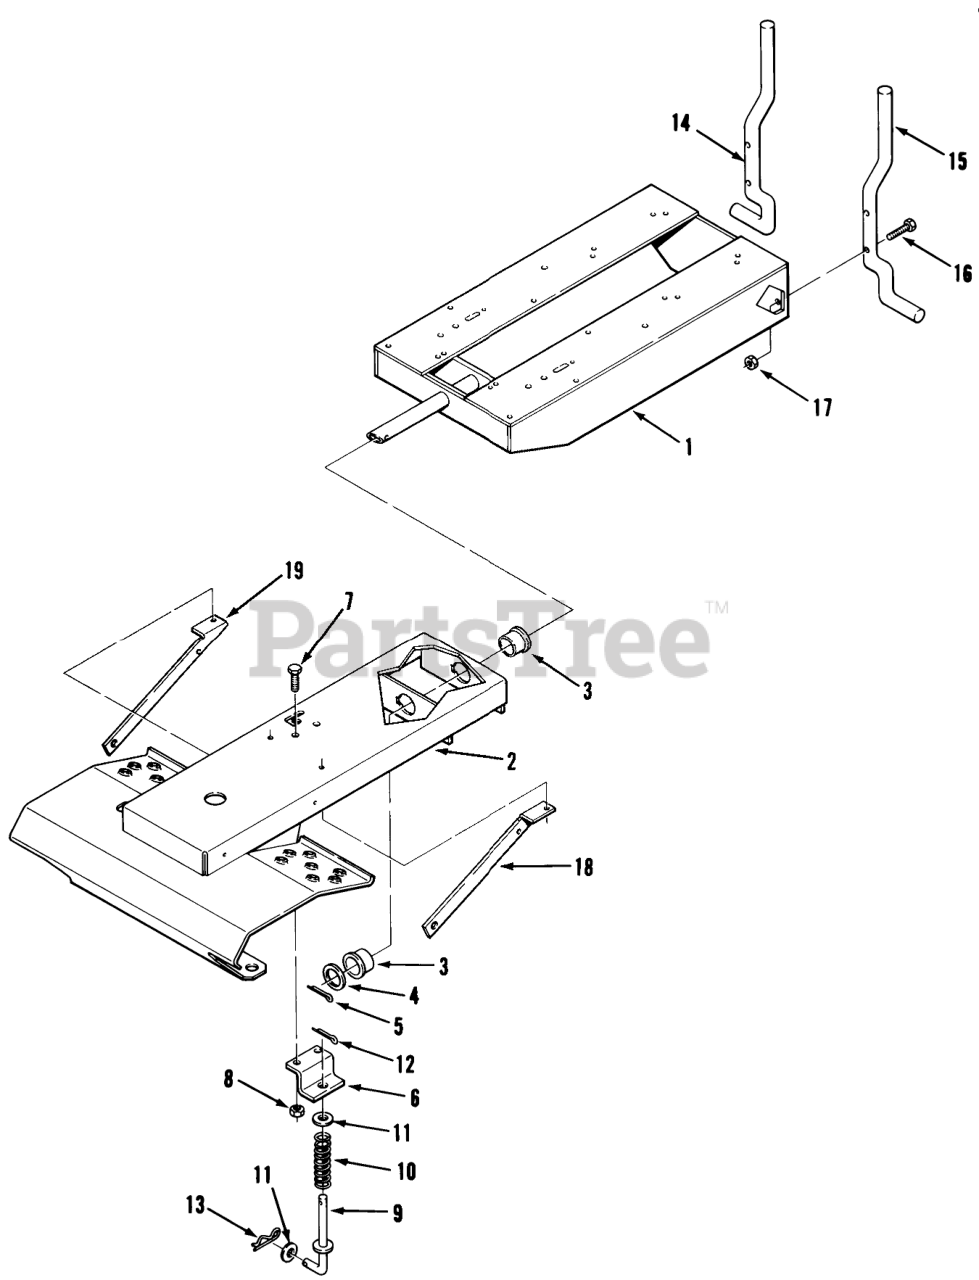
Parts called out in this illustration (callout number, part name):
1	Rear Frame Assy
2	Front Frame Assy
3	BEARING FLANGE
4	WASHER
5	Pin-Cotter
6	BRACKET R
7	Bolt
8	NUT
9	Rod Assembly
10	SPRING-COMPRESSION
11	Washer
12	Cotter Pin
13	Hairpin
14	BAR REAR RH
15	BAR REAR LH
16	Bolt
17	Nut
18	ASSY BRACE AXLE LH
19	ASSY BRACE AXLE RH
